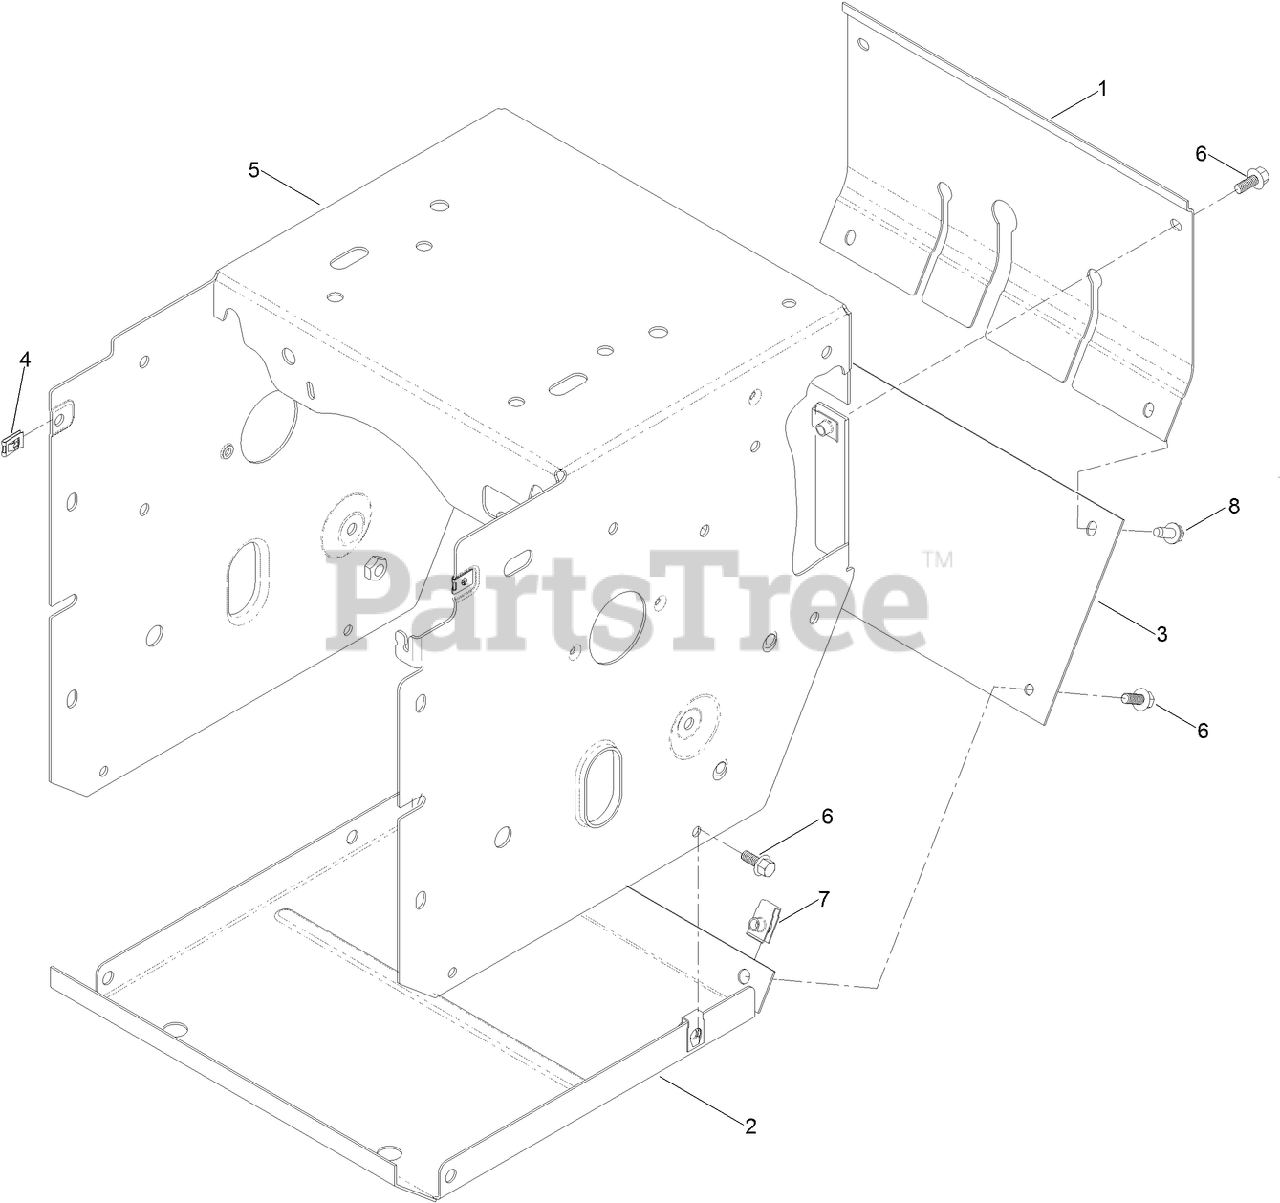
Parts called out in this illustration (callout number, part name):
1	COVER-UPPER
2	PAN-BOTTOM
3	COVER-LOWER
4	NUT-SPEED
5	FRAME-TRACTION
6	SCREW-HHF
8	SCREW-HWH
